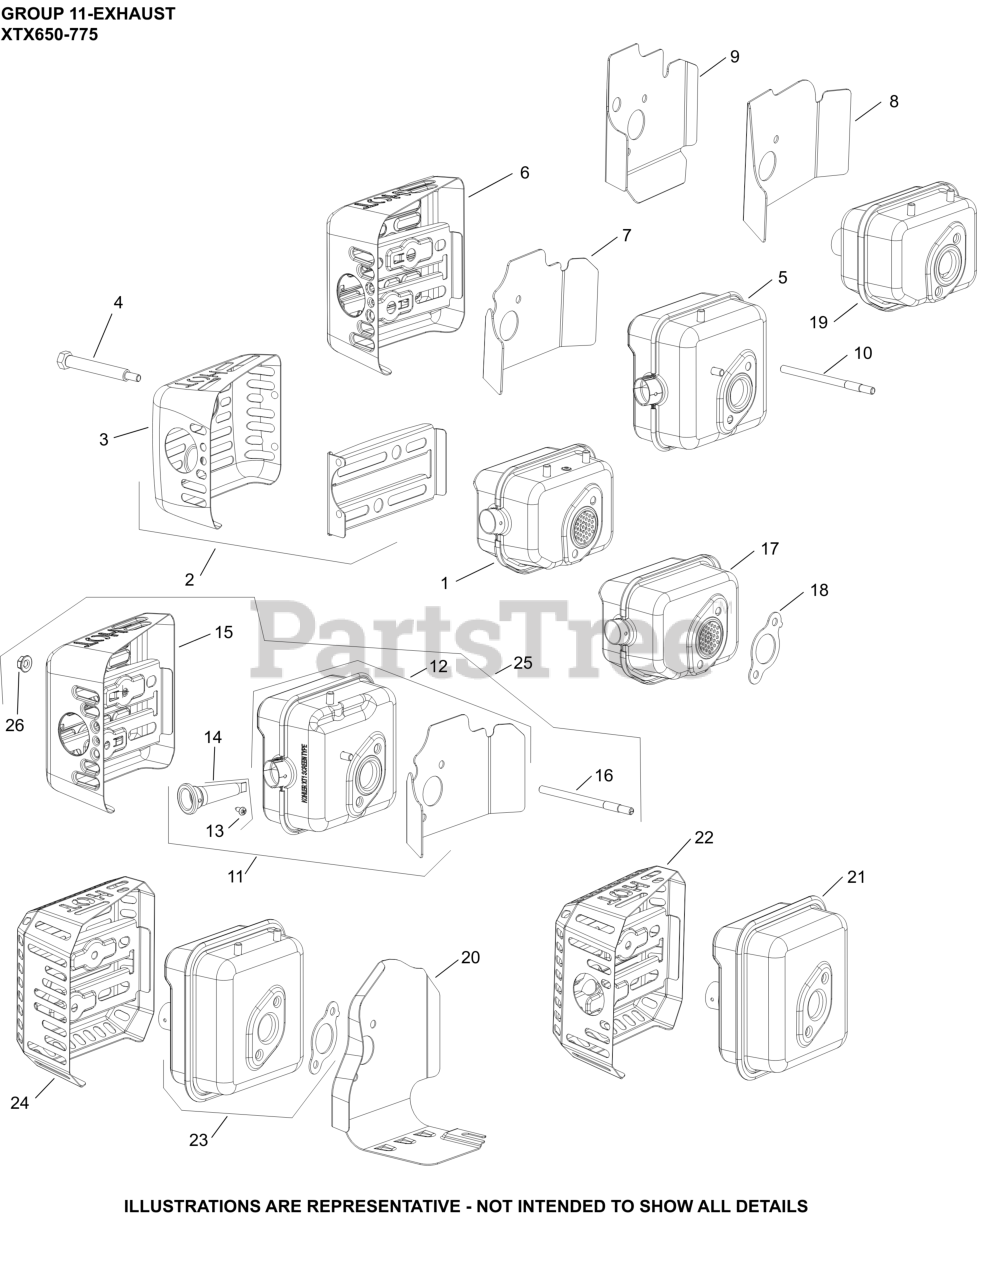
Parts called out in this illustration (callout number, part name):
2	GUARD, MUFFLER ASSEMBLY
3	GUARD, MUFFLER - DISCONTINUED
4	SCREW, SHOULDER
17	MUFFLER, ASSEMBLY
